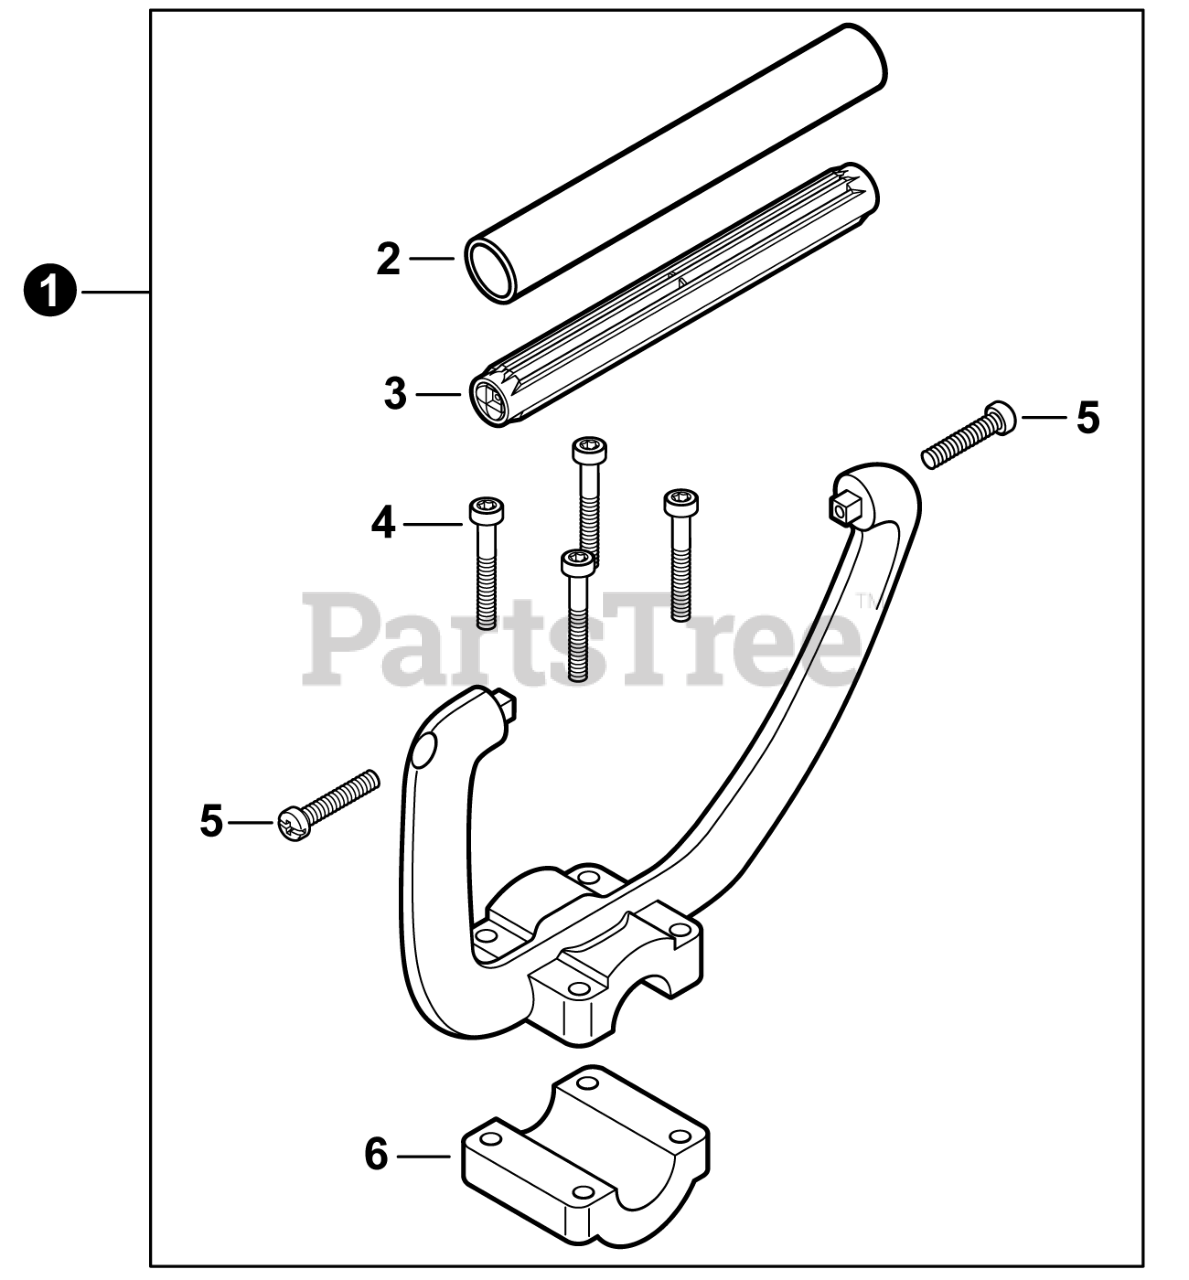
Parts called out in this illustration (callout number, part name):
1	HANDLE ASSY - SUPPORT
2	GRIP, HANDLE
4	BOLT, TORX 5x35
5	SCREW 5x30
6	BRACKET, HANDLE
